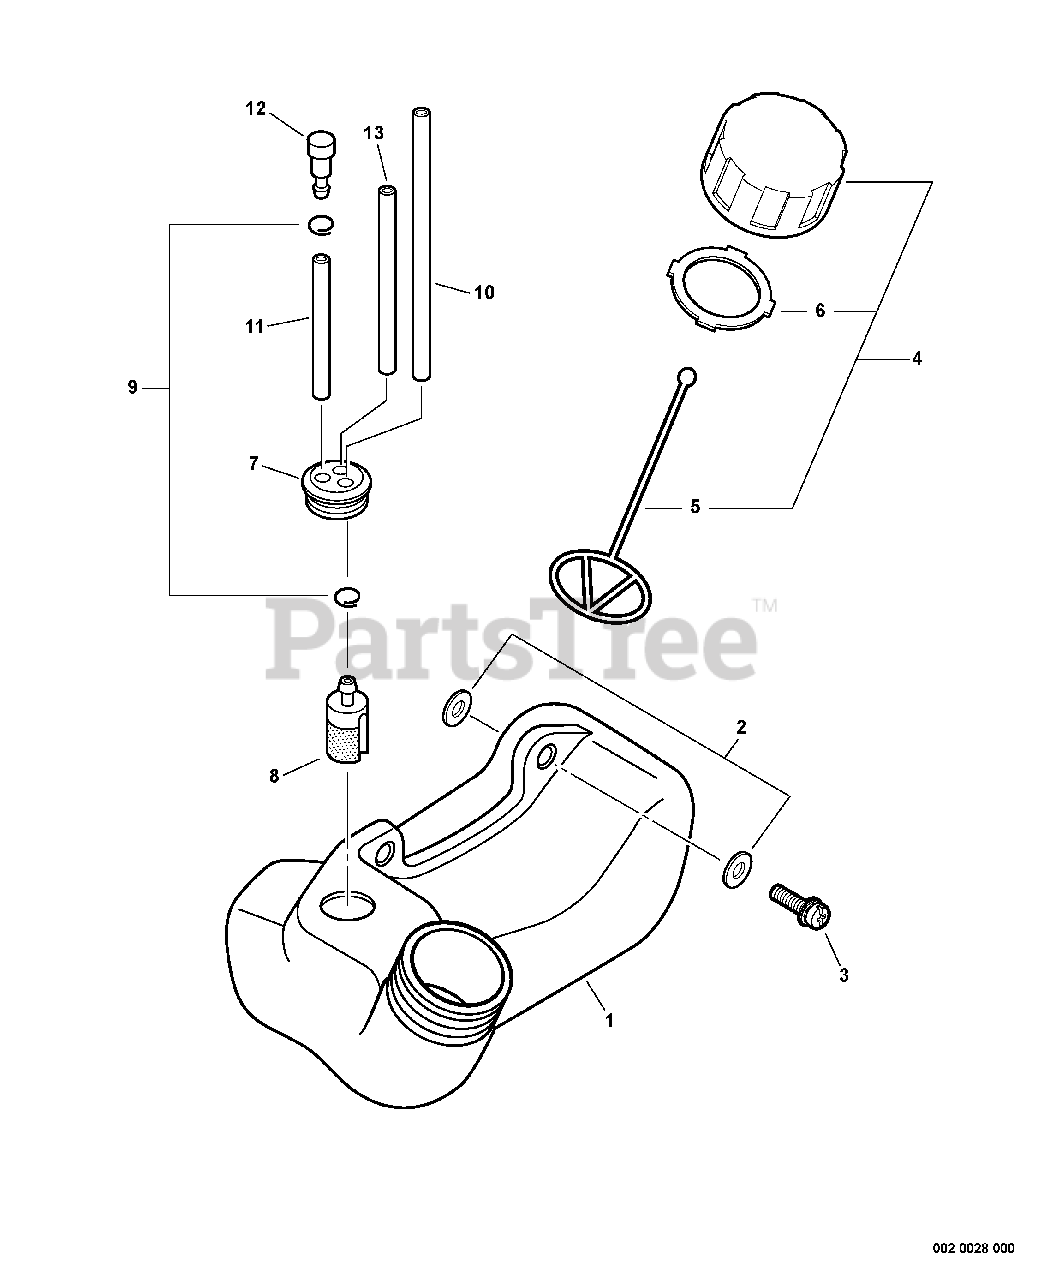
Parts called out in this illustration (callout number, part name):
1	TANK, FUEL
2	WASHER - 8
3	SCREW - 5X25
4	CAP ASSY
5	CONNECTOR, FUEL CAP
6	GASKET, CAP
7	GROMMET
8	FILTER, FUEL
9	CLIP - 6
10	PIPE - 3X5X195 -- BLACK
11	PIPE - 3X6X35 -- BLACK
12	VENT, FUEL TANK
13	PIPE - 3X6X110 -- CLEAR
